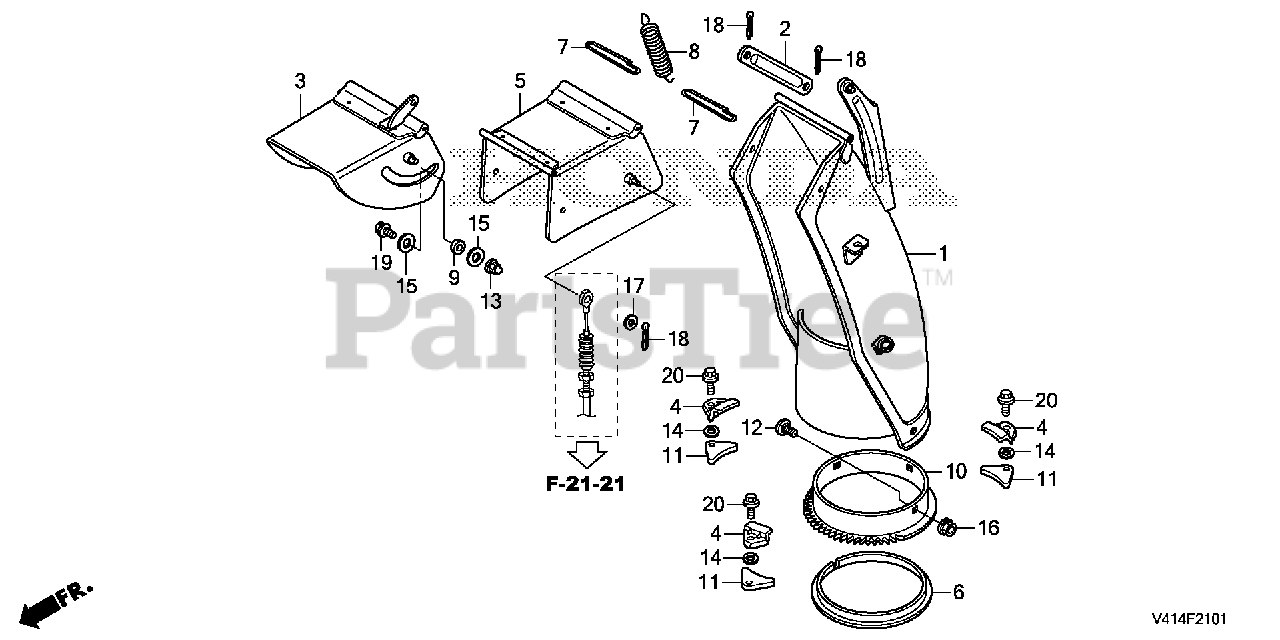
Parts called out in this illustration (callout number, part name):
1	CHUTE *R280* (POWER RED)
2	PLATE, CHUTE LINK
3	GUIDE, CHUTE
4	PLATE, CHUTE SETTING
5	GUIDE B, CHUTE
6	BUSH, CHUTE
7	PIN, CHUTE GUIDE
8	SPRING, CHUTE
9	COLLAR, CHUTE GUIDE
10	GEAR, CHUTE
11	PLATE, MOUNTING
12	BOLT, SPECIAL (8X14)
13	NUT, CAP (6MM)
14	WASHER, CHUTE SETTING
15	WASHER (10.2X22X1)
16	NUT, FLANGE (8MM)
17	WASHER, PLAIN (6MM)
18	PIN, SPLIT
19	BOLT, FLANGE (6X12)
20	BOLT, FLANGE (8X16)
